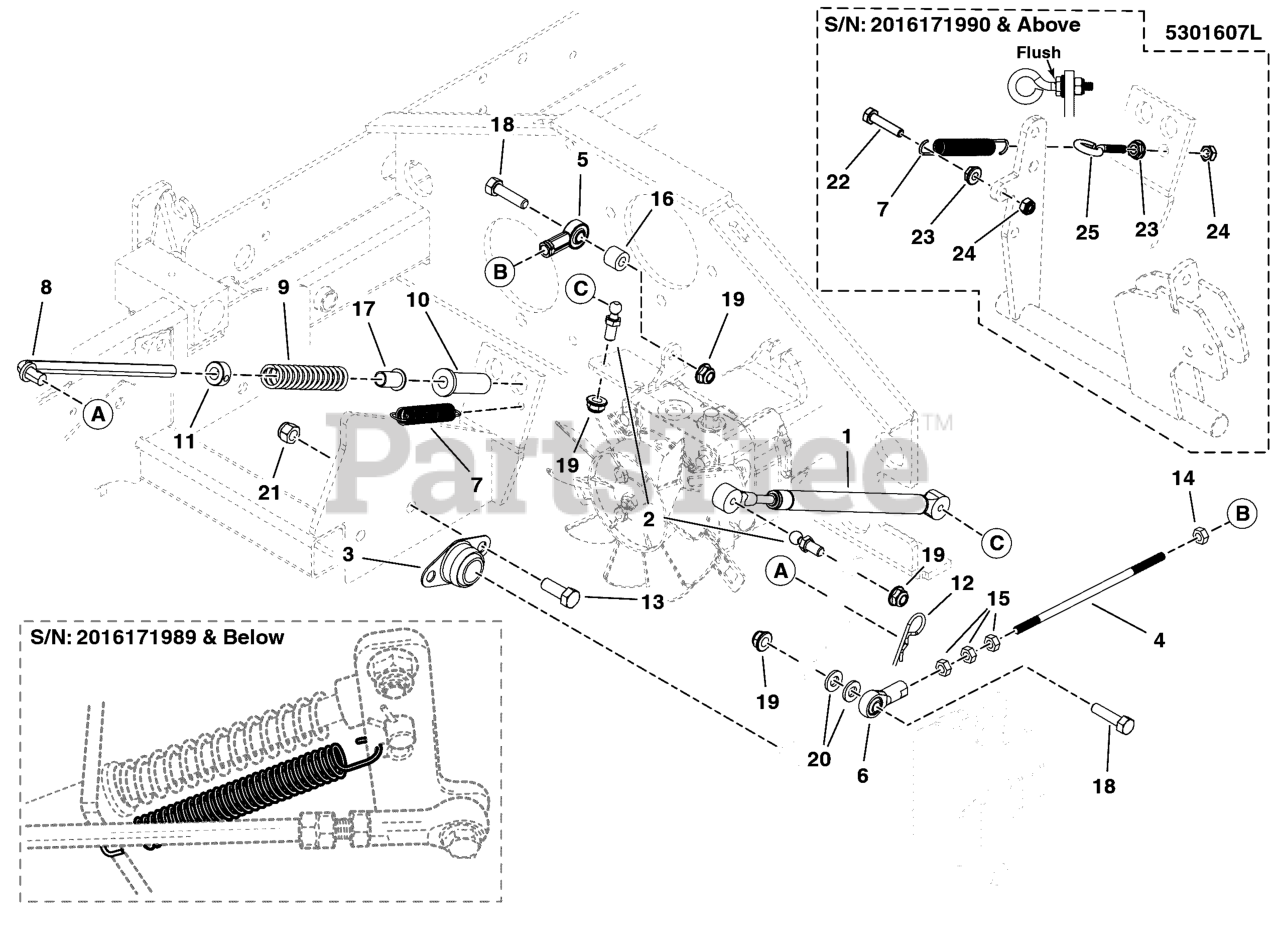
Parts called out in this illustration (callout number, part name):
1	DAMPENER, CONTROL,#(P6709/P3610)
2	10MM BALL STUD, 5/16-18 X 3/4 THDS
3	BEARING, BRONZE FLANGE, 3/4
4	ROD, 5/16 X 8.38, LH-RH, CZ
5	BALL JOINT 5/16-24 LH FEMALE BRONZE RACE
6	BALL JOINT 5/16-24 RH FEMALE BRONZE RACE
7	SPRING, EXTENSION
8	ROD, NEUTRAL RETURN
9	SPRING, REVERSE RETURN
10	FLANGED BUSHING, 3/8IDX.63ODX.8125FL
11	COLLAR, 3/8 SET
12	PIN, HAIR, .0585 X 1-1/8, 1/4 EYE, YZ
13	BOLT, 3/8-16 X 1" GD5 CZ
14	NUT, 5/16-24 HEX, LH
15	NUT, 5/16-24 HEX
16	SPACER-0.328IDX0.499ODX0.625LG PM
17	BUSHING, NYLON
18	BOLT, 5/16-18 X 1-1/4 GD5 YZ
19	NUT, 5/16-18 HEX NYLOCK FLANGE
20	WASHER, 5/16" SAE
21	NUT, 3/8-16 HEX NYLOCK FLANGE
22	BOLT, 1/4-20 X 1-1/4, GD5
23	NUT, 1/4-20 HEX SERR. FLANGE
24	NUT, 1/4-20 HEX NYLON LOCK
25	EYE BOLT, 1/4-20 X 2.5, 1THRD, .5EYE,CZ
